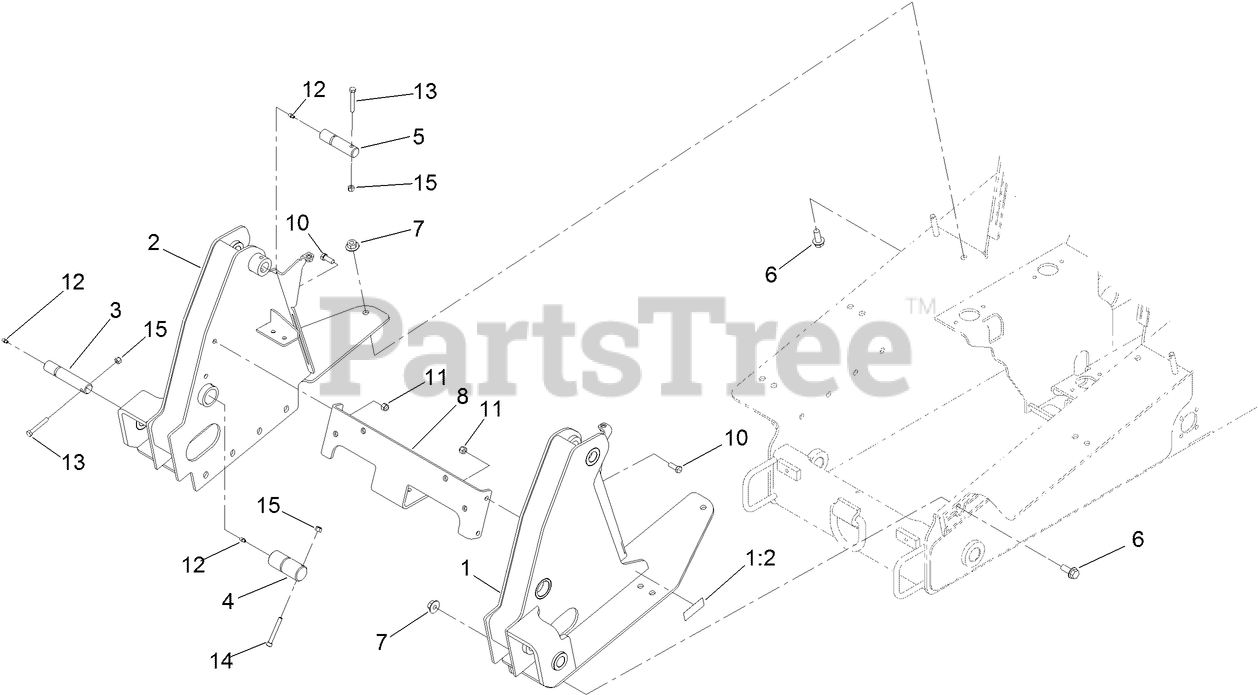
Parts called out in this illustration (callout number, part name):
1	TOWER-FRONT, LH
1:2	DECAL-SURFACE, HOT
2	TOWER, RH
3	PIN-HYD
4	PIN-ARM
5	PIN-LINK
6	SCREW-HHF
7	NUT-LOCK, FLANGE
8	PLATE-CROSS, TOWER
10	SCREW-HH
11	NUT-LOCK, NI
12	FITTING-GREASE
13	SCREW-HH
14	SCREW-HSH
15	NUT-LOCK, NI
